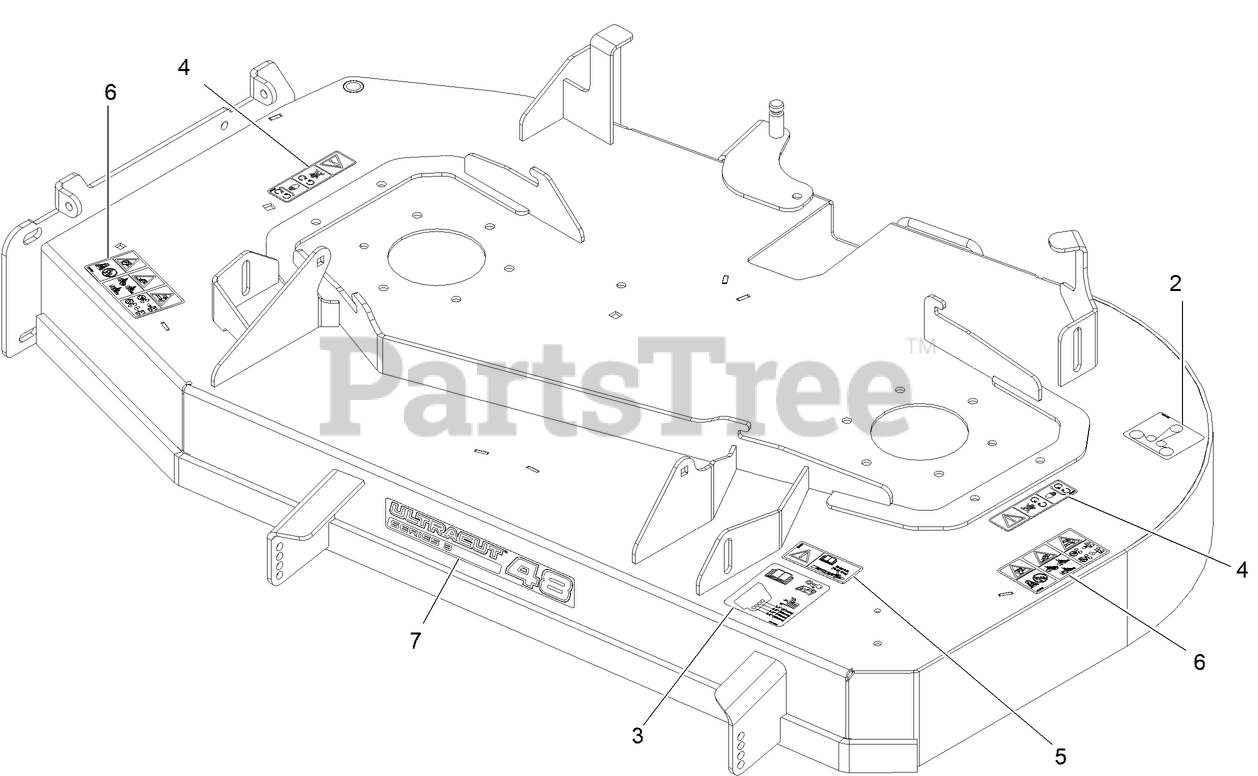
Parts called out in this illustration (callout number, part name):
2	DECAL-ROUTING, BELT
3	DECAL-ROLLER, ANTI-SCALP
4	DECAL-COVER, MISSING
5	DECAL-TORQUE, BOLT
6	DECAL-DANGER THROWN OBJECTS
7	DECAL-ULTRACUT 48 SERIES 3
